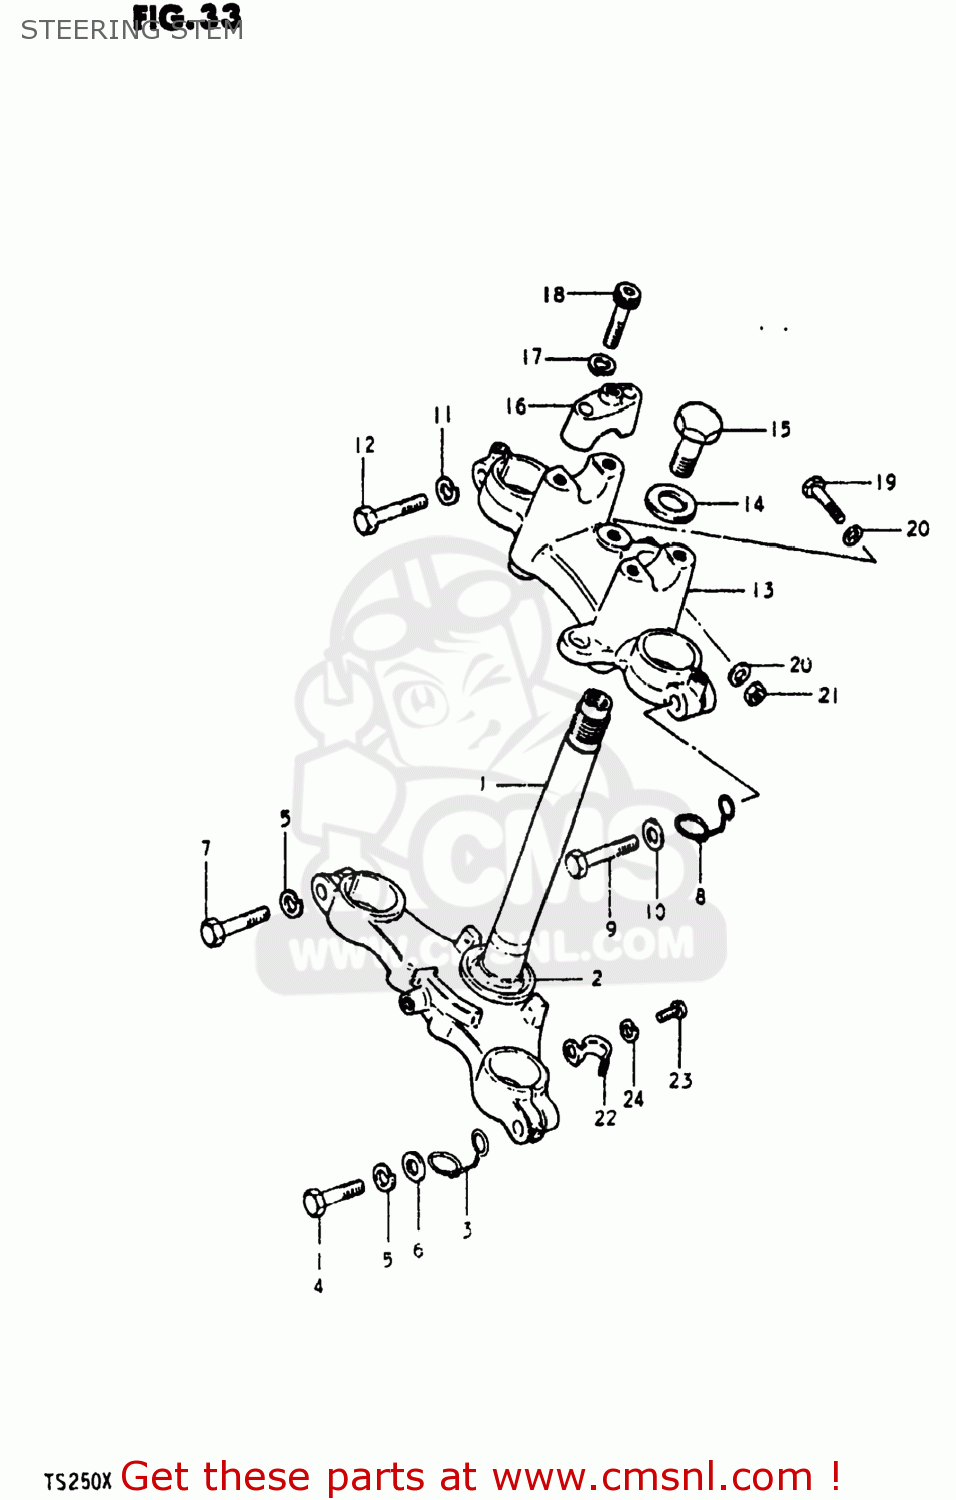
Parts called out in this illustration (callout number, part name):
1	STEM,STEERING
2	RACE,STEERING OUTER LWR
3	CLIP
4	BOLT 12X45
5	WASHER,LOCK 12
6	WASHER
7	BOLT
8	GUIDE,CABLE
9	BOLT 10X40
10	WASHER
11	LOCK WASHER
12	BOLT 10X40
13	HEAD,STEERING STEM
14	WASHER
15	BOLT,STEERING STEM HEAD
16	CLAMP,HANDLE HOLDER UPR
17	LOCK WASHER
18	BOLT 8X35
19	BOLT 8X55
20	WASHER
21	NUT
22	CLIP,BRAKE CABLE
23	SCREW
24	LOCK WASHER
